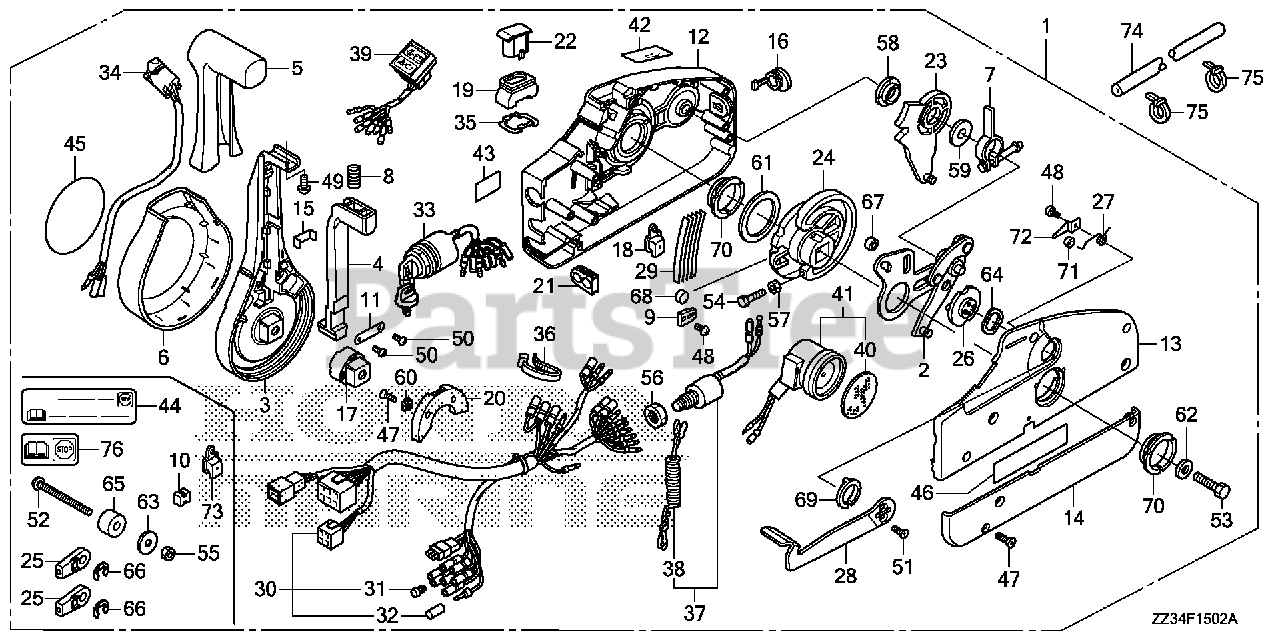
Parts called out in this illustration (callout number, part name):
1	BOX ASSY., REMOTE CONTROL (NHK MEC)
1	BOX ASSY., REMOTE CONTROL (TROLLING CONTROL)(NHK MEC)
2	PLATE ASSY.
3	LEVER, HAND
4	ARM, NEUTRAL LOCK
5	GRIP
6	COVER, LEVER
7	ARM ASSY., BRAKE
8	SPRING (2)
9	CLIP, DETENT
10	SPACER (1) (LOOSE PARTS)
11	BRACKET
12	HOUSING, FR.
13	HOUSING, RR.
14	PANEL, BACK
15	BRACKET, WIRE CLAMP
16	CAP, RUBBER
17	ADJUSTER
18	COVER, POWER TRIM-TILT WIRE
19	SEAL, RUBBER
20	HOLDER, NEUTRAL LOCK
21	GROMMET, WIRE (14)
22	CAP, TROLLING CONTROL SWITCH BLANK
23	GEAR ASSY., SHIFT
24	GEAR, DRIVE
25	TERMINAL, CABLE (LOOSE PARTS)
26	DRUM ASSY., FREE THROTTLE
27	SPRING (1)
28	LEVER, FREE THROTTLE
29	SPRING, DETENT
30	CABLE ASSY., REMOTE CONTROL (B)
31	PLUG, CONNECTOR (INNER)
32	PLUG, CONNECTOR (OUTER)
33	SWITCH ASSY., COMBINATION
34	SWITCH ASSY., POWER TRIM-TILT
35	PLATE, SWITCH
36	BAND, WIRE
37	SWITCH ASSY., EMERGENCY STOP
38	WIRE, EMERGENCY
39	LAMP ASSY., INDICATION
40	PLATE, TURN SIGNAL BUZZER
41	BUZZER, WARNING
42	MARK, FAST IDLE
43	MARK, EMERGENCY STOP (US)
44	MARK, EMERGENCY STOP (US) (LOOSE PARTS)
45	MARK, EMBLEM
46	LABEL, SIGP
47	SCREW (5X18)
48	SCREW (4X6)
49	SCREW (5X10)
50	SCREW (4X10)
51	SCREW (5X12)
52	SCREW (6X90) (LOOSE PARTS)
53	BOLT (8X50)
54	BOLT (5X25)
55	NUT (6MM) (LOOSE PARTS)
56	NUT, HEX. (16MM)
57	NUT (5MM)
58	BEARING (1)
59	WASHER (3)
60	WASHER (4)
61	WASHER (5)
62	WASHER (8MM)
63	WASHER (7) (LOOSE PARTS)
64	WASHER, WAVE
65	SPACER (2) (LOOSE PARTS)
66	E-RING (6MM) (LOOSE PARTS)
67	ROLLER, DRIVE GEAR CAM
68	ROLLER
69	BEARING (2)
70	BEARING (3)
71	ROLLER, FREE THROTTLE
72	CLIP, ROLLER
73	COVER, POWER TRIM-TILT WIRE (LOOSE PARTS)
74	TUBE, CORRUGATE (28MM)
75	BAND, SELF-LOCK
